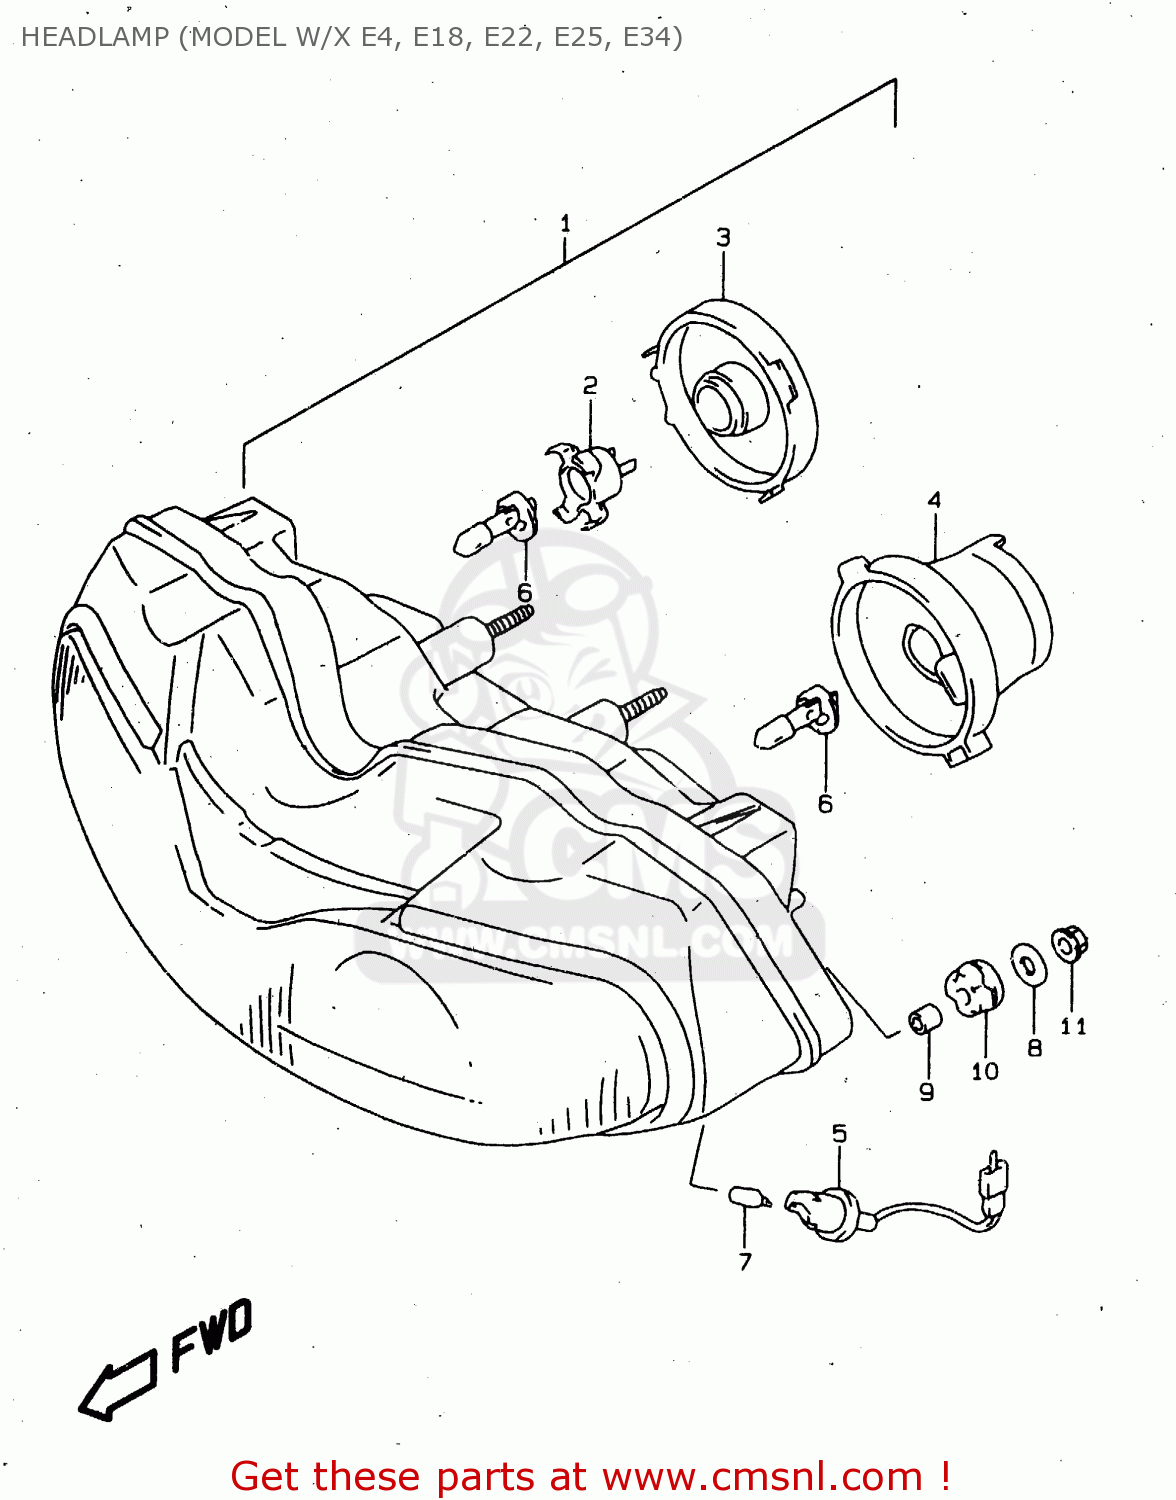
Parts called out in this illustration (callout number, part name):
1	HEADLAMP ASSY
2	ADAPTER ASSY
3	COVER,SOCKET
4	SOCKET & CORD ASSY
5	SOCKET ASSY
6	BULB(12V55W/H1/P14.5S/OSRA,PHI
7	BULB(12V5W)
8	WASHER(6.5X20X1.6)
9	SPACER(6.5X9X12.5)
10	CUSHION
11	NUT
